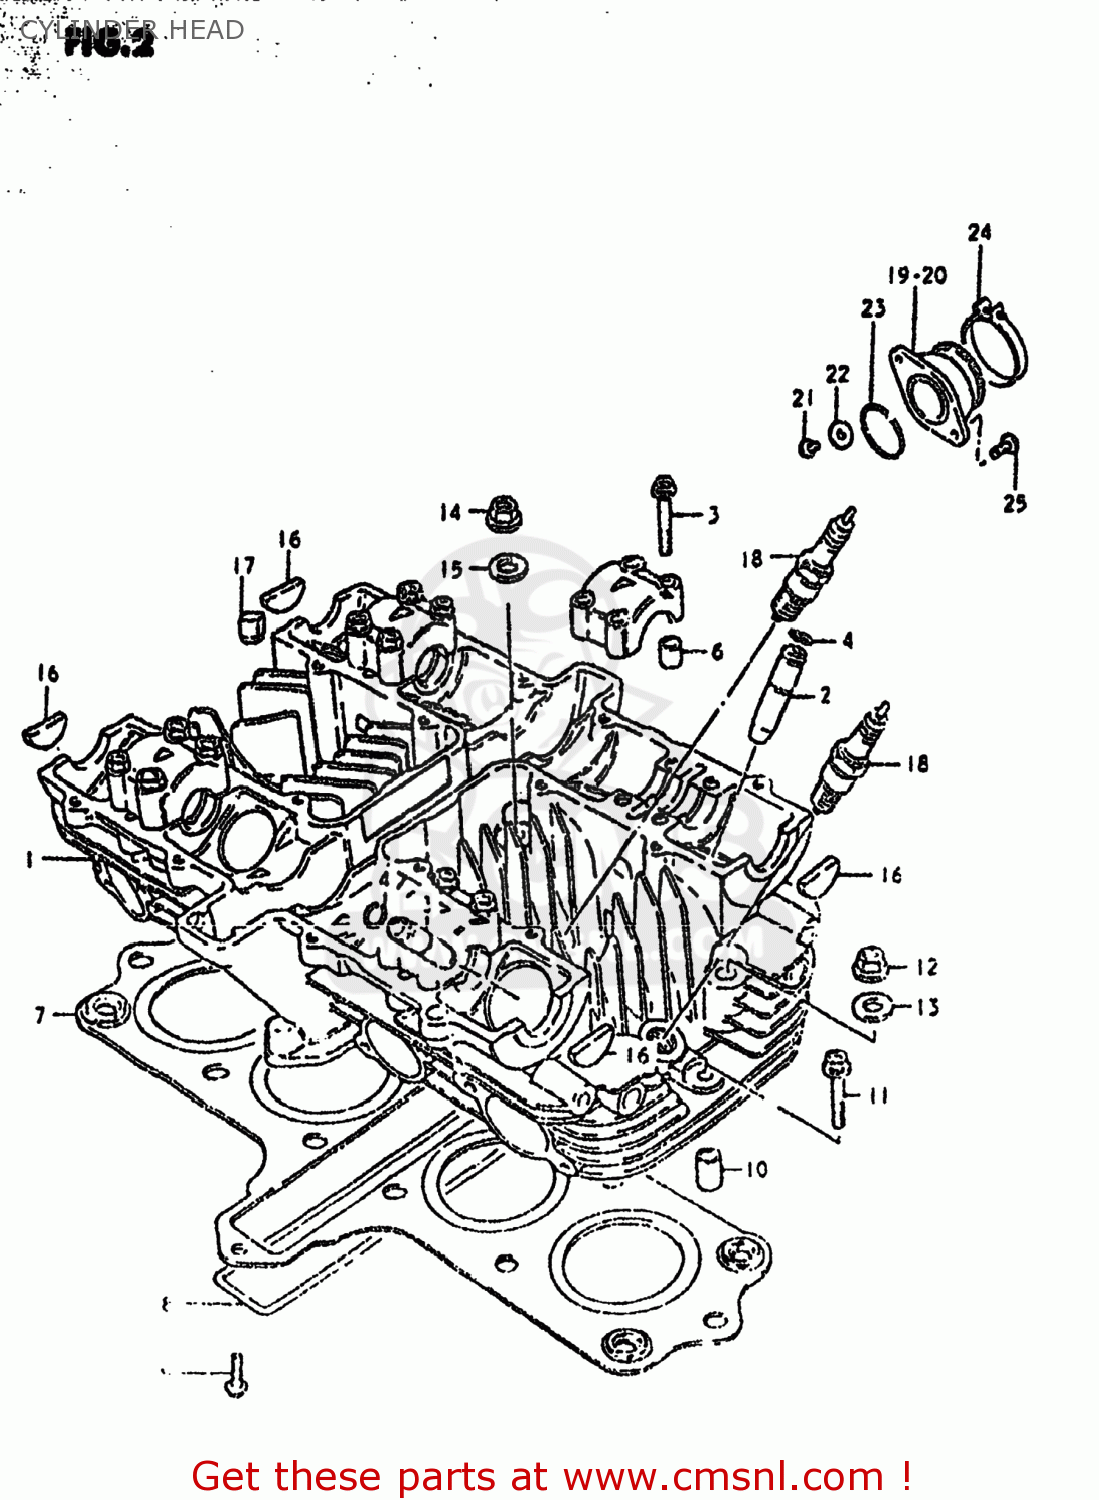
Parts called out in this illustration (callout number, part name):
1	HEAD ASSEMBLY,CYLINDER
2	GUIDE,INTAKE VALVE
3	GUIDE,EXHAUST VALVE
4	RING,SNAP
5	BOLT(6X39)
6	PIN(6.2X8X11)
7	GASKET,CYLINDER HEAD (MCA)
8	O RING(D:3,ID:26X157)
9	BOLT
10	PIN
11	BOLT,UNDER
12	NUT
13	GASKET (NAS)
14	NUT
15	WASHER(8.5X19X2.3)
16	PLUG
17	PAD
18	SPARK PLUG
19	PIPE,INTAKE,R
20	PIPE,INTAKE,L
21	BOLT
22	WASHER
23	O-RING
24	CLAMP
25	SCREW
